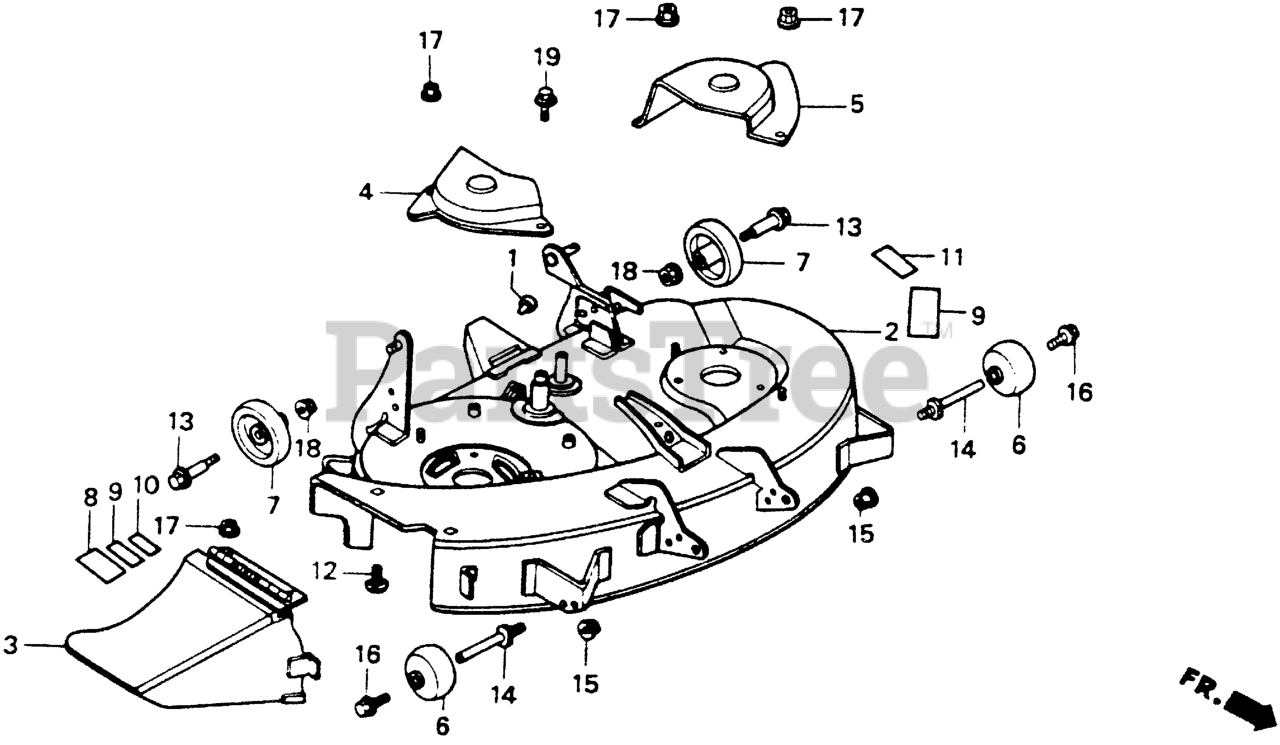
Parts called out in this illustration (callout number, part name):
1	RUBBER, STOPPER
2	HOUSING, CUTTER (NOT AVAILABLE)
3	ADAPTER, DISCHARGE *NH190M* (VINTAGE GRAY METALLIC)
4	COVER, R. BELT *NH190M* (VINTAGE GRAY METALLIC)
5	COVER, L. BELT *NH190M* (VINTAGE GRAY METALLIC) (NOT AVAILABLE)
6	ROLLER, ANTI-SCALP
7	ROLLER, RR. ANTI-SCALP
8	LABEL B, WARNING (ENGLISH)
9	LABEL A, WARNING (ENGLISH)
10	MARK, INCH SIZE (38)
11	LABEL D, CAUTION (ENGLISH)
12	BOLT, SPECIAL (9X15)
13	BOLT, ANTI-SCALP ROLLER
14	SHAFT, ANTI-SCALP ROLLER
15	NUT, SELF-LOCK (12MM)
16	BOLT-WASHER (8X16)
17	NUT, FLANGE (8MM)
18	NUT, FLANGE (10MM)
19	BOLT, FLANGE (8X14)
